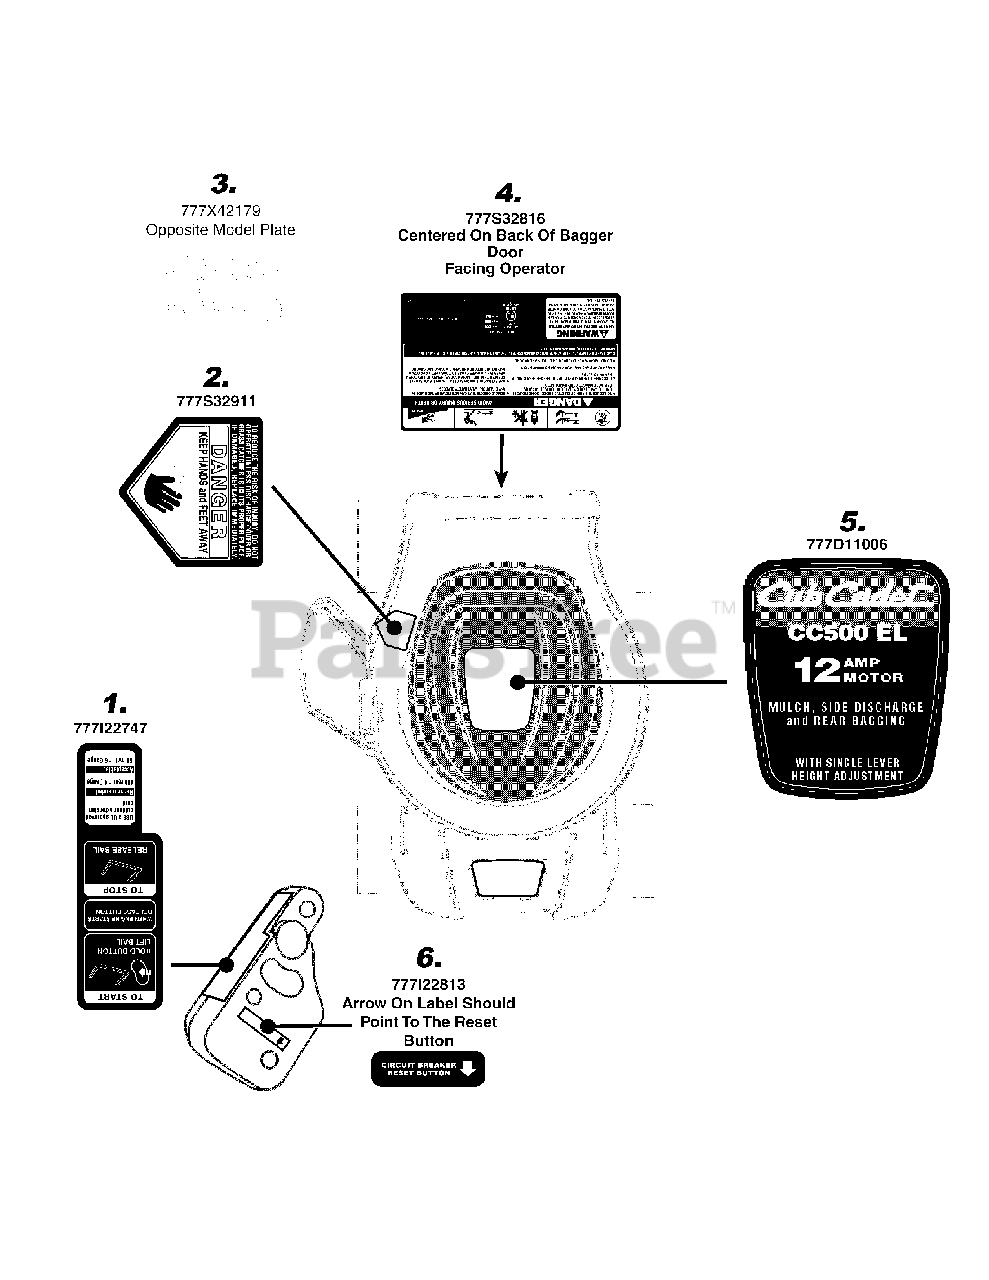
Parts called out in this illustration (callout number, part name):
1	LABEL-SWITCH START
2	LABEL-CUT FINGER
3	LABEL-CUB HOTLINE
4	LABEL-REAR SAFETY
5	LABEL-CC500 EL
6	LABEL-BREAKER RESET
